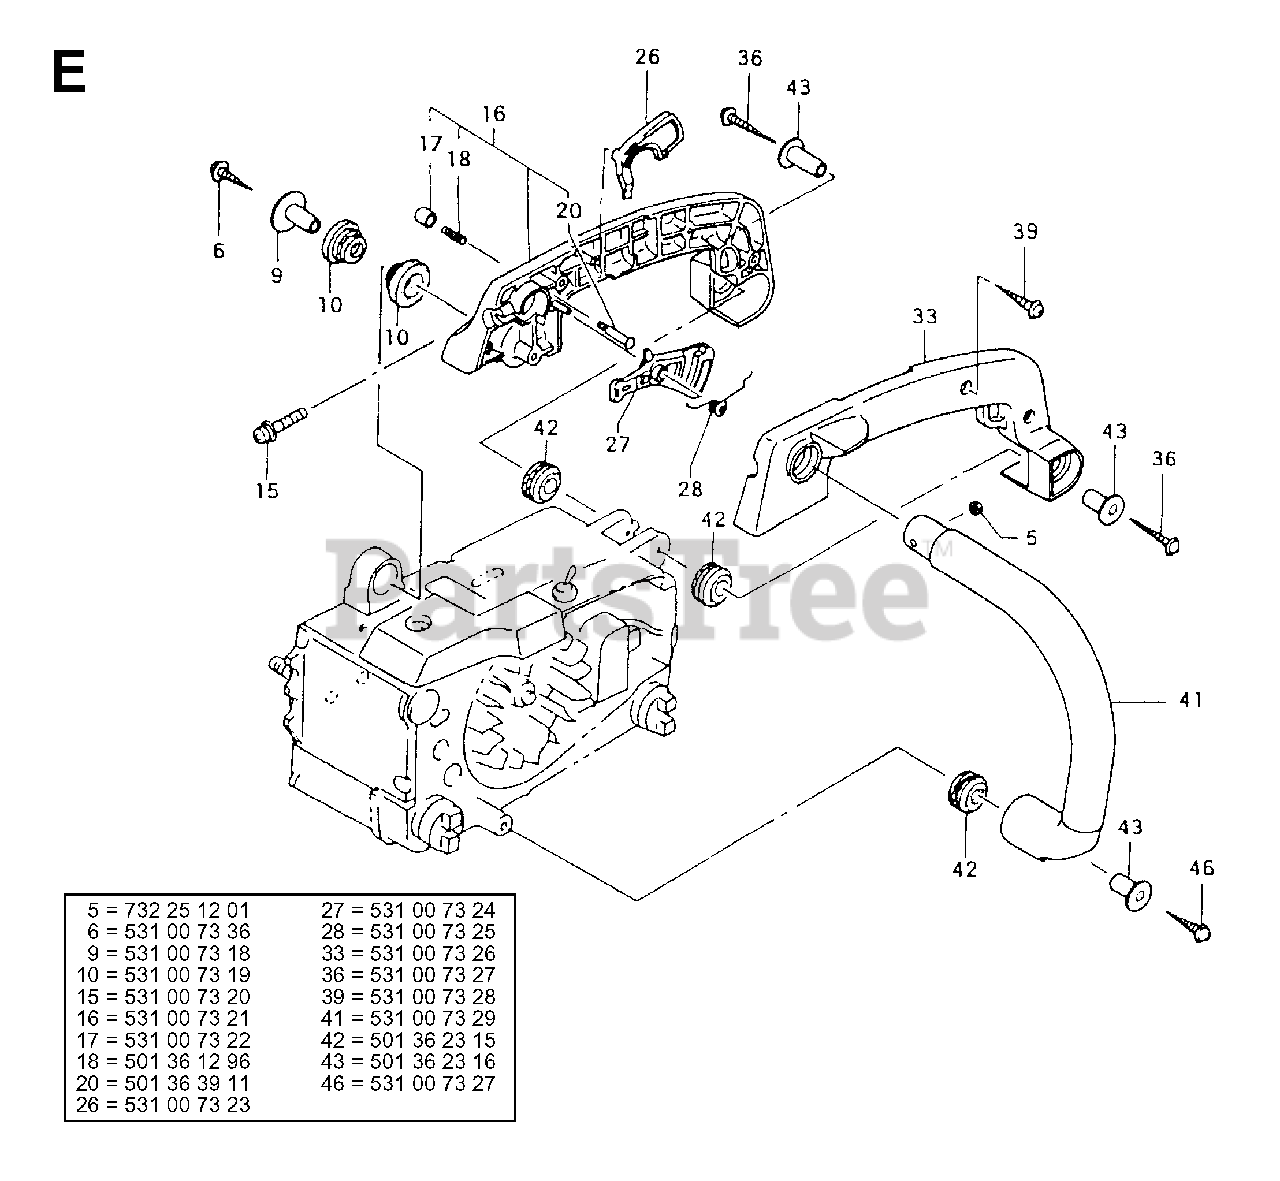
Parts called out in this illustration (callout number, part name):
5	NUT M4
10	VIBRATION ABSORBER
26	THROTTLE LOCK
